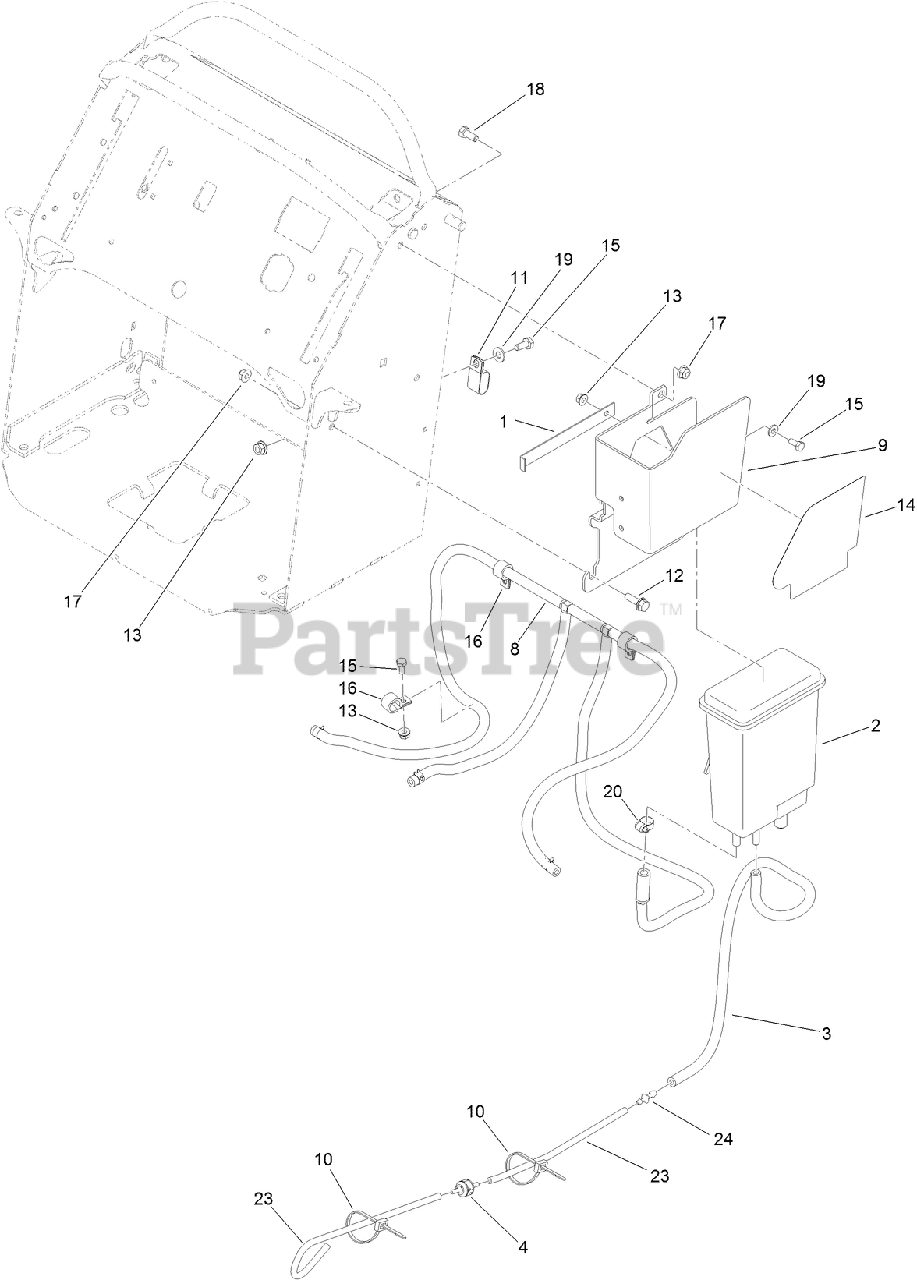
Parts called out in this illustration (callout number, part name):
1	PLATE-LOC
2	CANISTER-CARBON, 1200CC
3	HOSE-FUEL
4	VALVE-CHECK, VACUUM
8	VENT HOSE ASM
9	PLATE- ADAPTER
10	TIE-CABLE
11	CLAMP-TUBE, DOUBLE
12	SCREW-HHF
13	NUT-HHF
14	DECAL-SERVICE/SPARK ARREST
15	SCREW-HH
16	CLAMP-CABLE
17	NUT-HF, NI
18	SCREW-HH
19	WASHER-FLAT
20	CLAMP-WORM
23	HOSE-VENT, FORMED
24	FITTING-STRAIGHT
